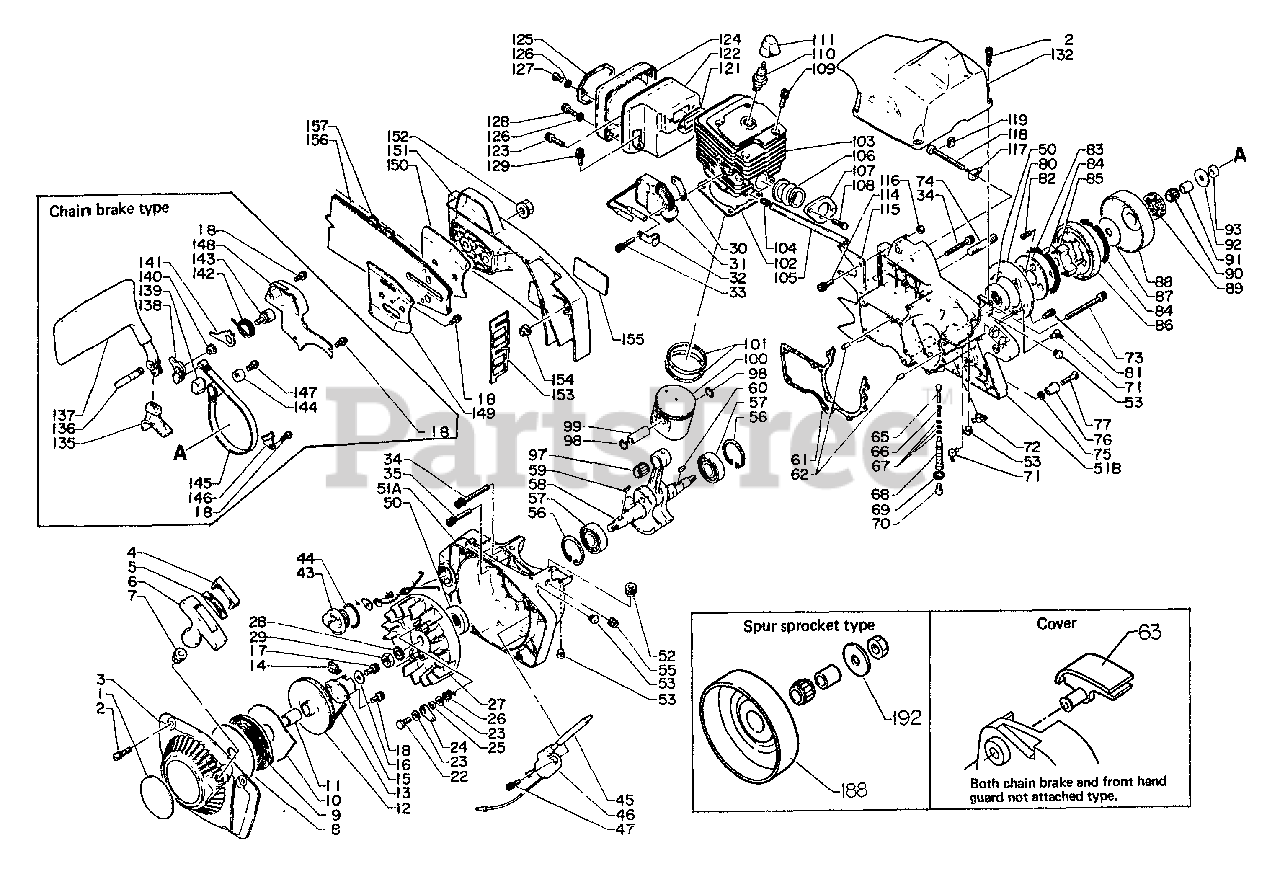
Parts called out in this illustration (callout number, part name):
1	LABEL
2	SCREW - 5X20
3	CASE, STARTER
4	CAP
6	GRIP, STARTER
7	GUIDE, ROPE
8	PLATE, STARTER
9	SPRING, REWIND
10	PLATE, STARTER
12	REEL, ROPE
13	ROPE, STARTER
14	RETAINER, ROPE
15	CATCHER, PAWL
17	SCREW - 5X15
18	SCREW - 4X12
22	BOLT - 6X16
23	WASHER - 6
24	PAWL, STARTER
26	SPRING, RETURN
27	FLYWHEEL
28	WASHER - 10
30	SPACER
31	COIL, IGNITION
32	CLAMP
33	SCREW - 5X25
34	SCREW - 5X50
35	SCREW - 5X35
43	CAP ASSY
44	O-RING - 25
46	COIL, IGNITION
47	SCREW - 4X16
50	SEAL, OIL
51	CRANKCASE KIT
51A	CRANKCASE KIT
51B	CRANKCASE KIT
53	CUSHION
55	GROMMET
56	RING, RETAINING - 40
57	BEARING, BALL - 6203
58	CRANKSHAFT ASSY
60	KEY - 3X14
61	GASKET, CRANKCASE
62	PIN - LOCATING
63	COVER
65	PUMP KIT
67	O-RING - 5
69	LOCKWASHER
70	SCREW
71	FITTING, GREASE
72	CONNECTOR
73	SCREW - 5X65
74	STUD, GUIDE BAR
75	WASHER - 5
76	CATCHER, CHAIN
77	SCREW - 5X25
80	SEAL, DUST
81	SCREW - 4X10
82	SCREW - 5X12
83	PLATE, CLUTCH
84	SPRING, CLUTCH
85	HUB, CLUTCH
86	SHOE, CLUTCH
87	WASHER, CLUTCH
88	DRUM, CLUTCH
89	SPROCKET, RIM
90	BEARING, NEEDLE
92	WASHER, CLUTCH
93	LOCKNUT
97	BEARING, NEEDLE
98	RING, RETAINING
99	PIN, PISTON
100	PISTON
101	RING, PISTON
102	GASKET, CYLINDER
103	CYLINDER
104	CONNECTOR
105	PIPE - OIL
106	BELLOWS, INTAKE
107	RETAINER
108	SCREW - 5X20
109	SCREW - 6X20
110	SPARK PLUG -- BPM-7A
110	SPARK PLUG -- BPMR-7A
111	CAP, SPARK PLUG
114	SCREW - 5X15
115	SPIKE
116	LOCKNUT - 5
117	TENSIONER, CHAIN
118	SCREW, TENSIONER
121	GASKET, EXHAUST
122	CASE, MUFFLER
123	SCREW - 5X18
124	MUFFLER
125	LID, MUFFLER
126	LOCKWASHER - 5
127	SCREW - 5X8
128	SCREW - 5X16
129	SCREW - 5X12
132	COVER, ENGINE
135	COVER, BRAKE
137	HANDLE, BRAKE
138	CONNECTOR
139	SEAL, DUST
142	SPRING, RETURN
144	ADJUSTER, BRAKE BAND
145	BAND, BRAKE
146	RETAINER, BRAKE BAND
147	SCREW - 5X14
148	COVER, BRAKE
149	PLATE, GUIDE - INNER
150	PLATE, GUIDE - OUTER
151	GUARD, SPROCKET
152	NUT - FLANGE
154	PIN - LOCATING
155	LABEL - ECHO
156	GUIDE BAR - 65H63
157	SAW CHAIN - 52CP80E
188	DRUM, CLUTCH
192	WASHER
